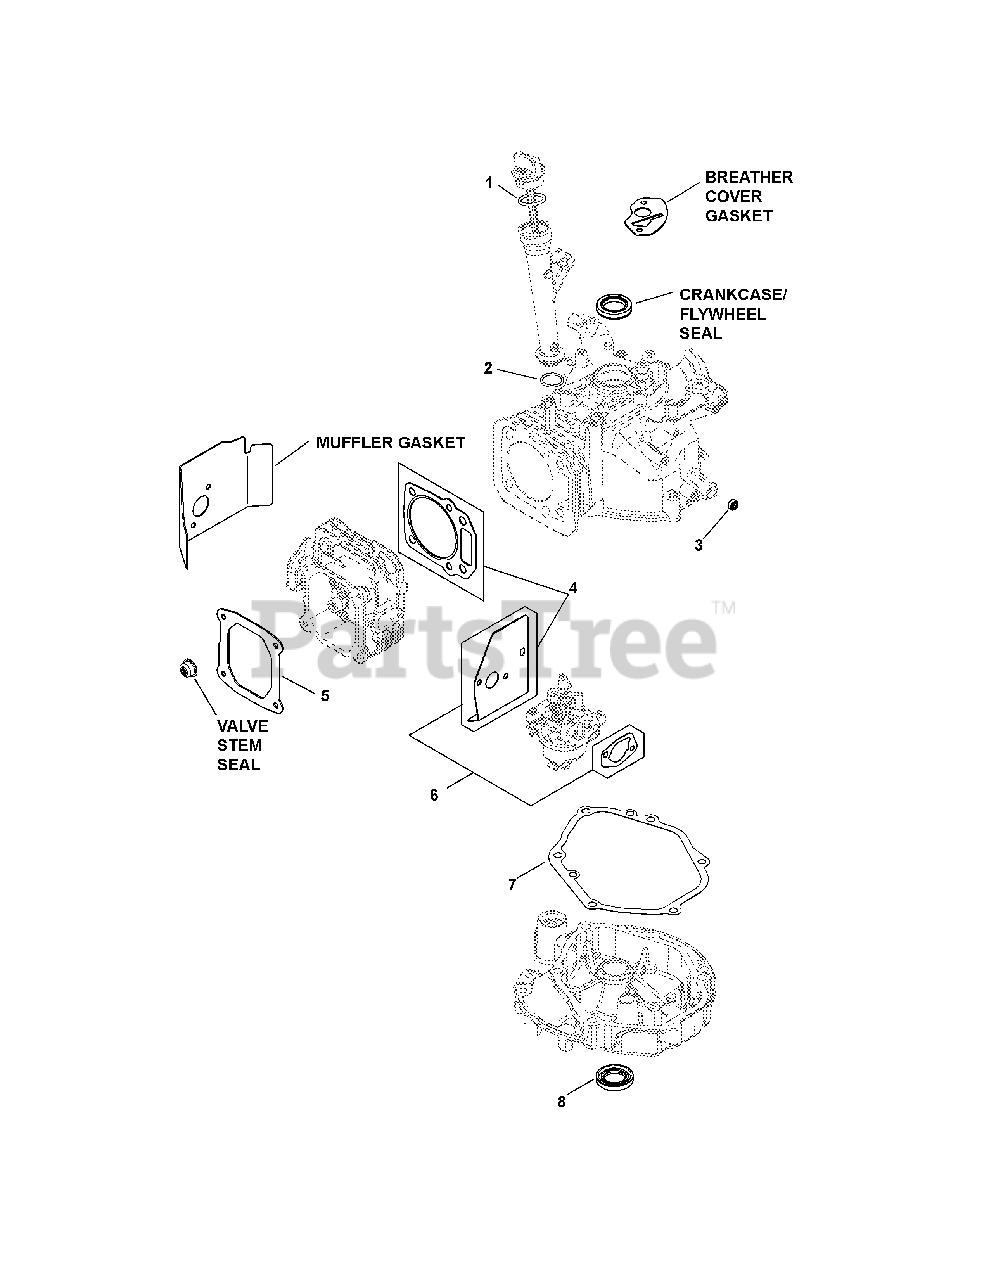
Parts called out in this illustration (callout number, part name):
1	O-Ring, Dipstick
2	O-Ring, Oil Fill Tube
4	Kit, Head Gasket (Includes 6, Muffler Gasket)
5	Gasket, Valve Cover
6	Kit, Carb Gasket
7	Gasket, Oil Pan
8	Seal, Oil (Pto)
